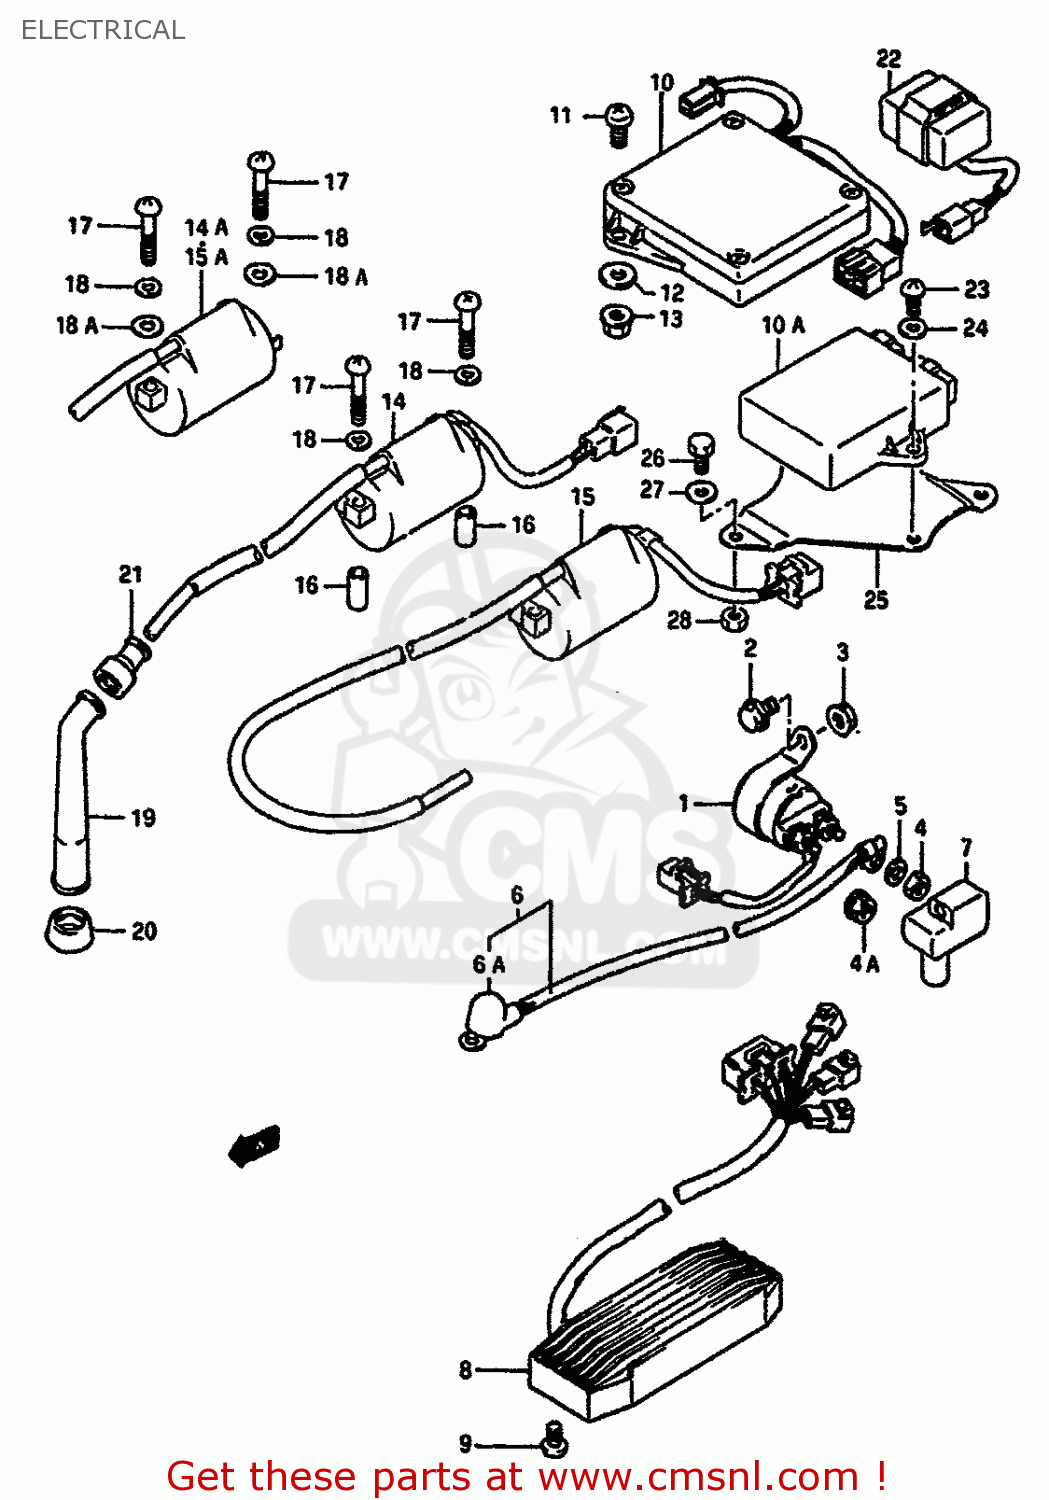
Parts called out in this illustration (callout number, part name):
1	RELAY ASSEMBLY,STARTING MOTOR
2	BOLT
3	NUT
4	NUT
4A	NUT
5	WASHER,LOCK
6	WIRE,STARTER MOTOR LEAD
6A	CAP,STARTER MOTOR TERMINAL
7	CAP,STARTER RELAY
8	RECTIFIER ASSY
9	BOLT
10	IGNITOR UNIT
10A	IGNITER UNIT ASSEMBLY
11	SCREW
12	WASHER(6.5X20X2)
13	NUT
14	COIL ASSEMBLY,IGNITION
14A	COIL ASSEMBLY,IGNITION
15	COIL ASSEMBLY,IGNITION
15A	COIL ASSEMBLY,IGNITION
16	SPACER(6.4X10X19)
17	SCREW (5X38)
18	LOCK WASHER
18A	WASHER
19	CAP,SPARK PLUG
20	SEAL,SPARK PLUG CAP
21	SEAL,HIGH TENSION CORD
22	RELAY ASSY,FUEL CUT
23	SCREW
24	WASHER, LOWER
25	PLATE,IGNITOR FITING
26	BOLT
27	WASHER,LOCK
28	NUT
